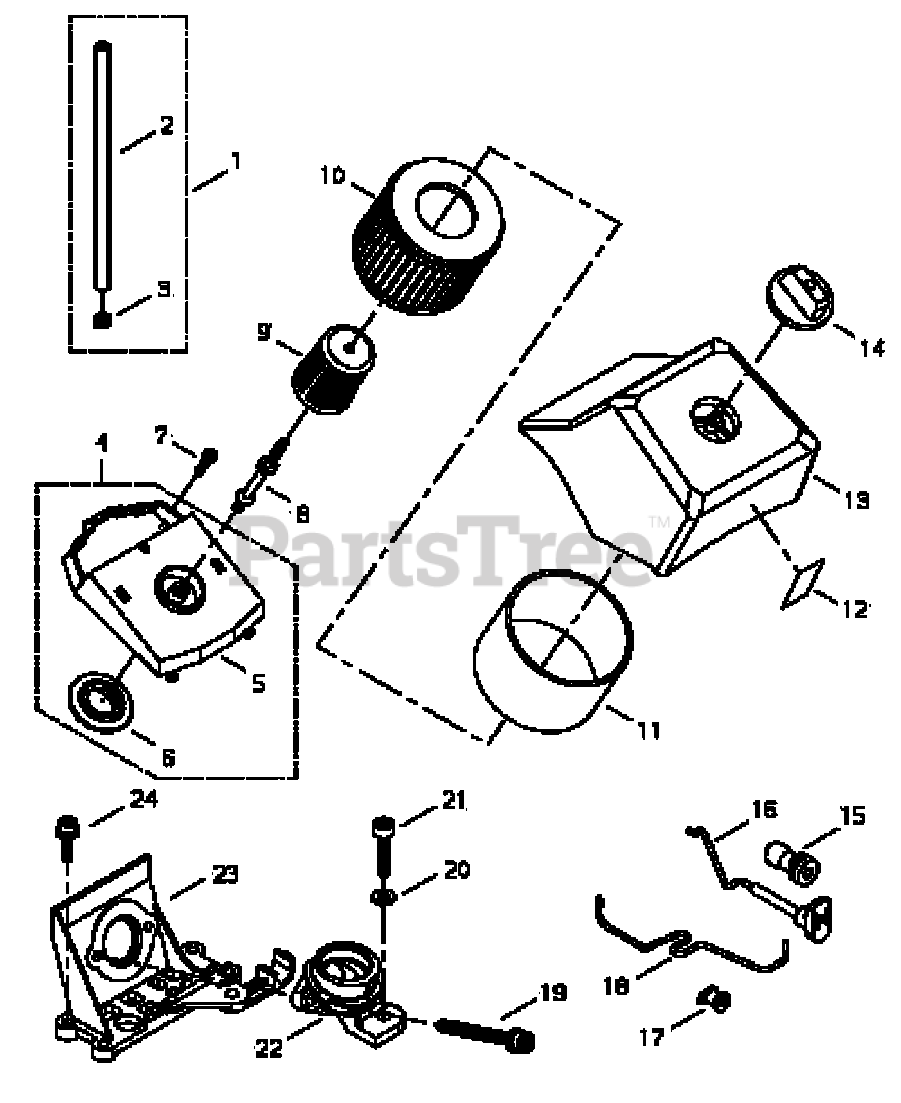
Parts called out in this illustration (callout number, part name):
1	PIPE, PULSE
2	PIPE, PULSE
3	CLIP
4	BASE ASSY, AIR FILTER
5	BASE ASSY, AIR FILTER
6	BOOT
7	BOLT 5×16
8	BOLT
9	FILTER, AIR
10	FILTER, AIR
11	PRE-FILTER, FOAM
12	LABEL, CAUTION I
13	COVER, AIR FILTER
14	KNOB
15	GROMMET, CHOKE
16	ROD, CHOKE
17	GROMMET
18	ROD, THROTTLE
19	BOLT M5×50
20	WASHER 5.5×12×0.8
21	BOLT M5×18
22	ELBOW
23	MOUNT
24	BOLT M4×16
